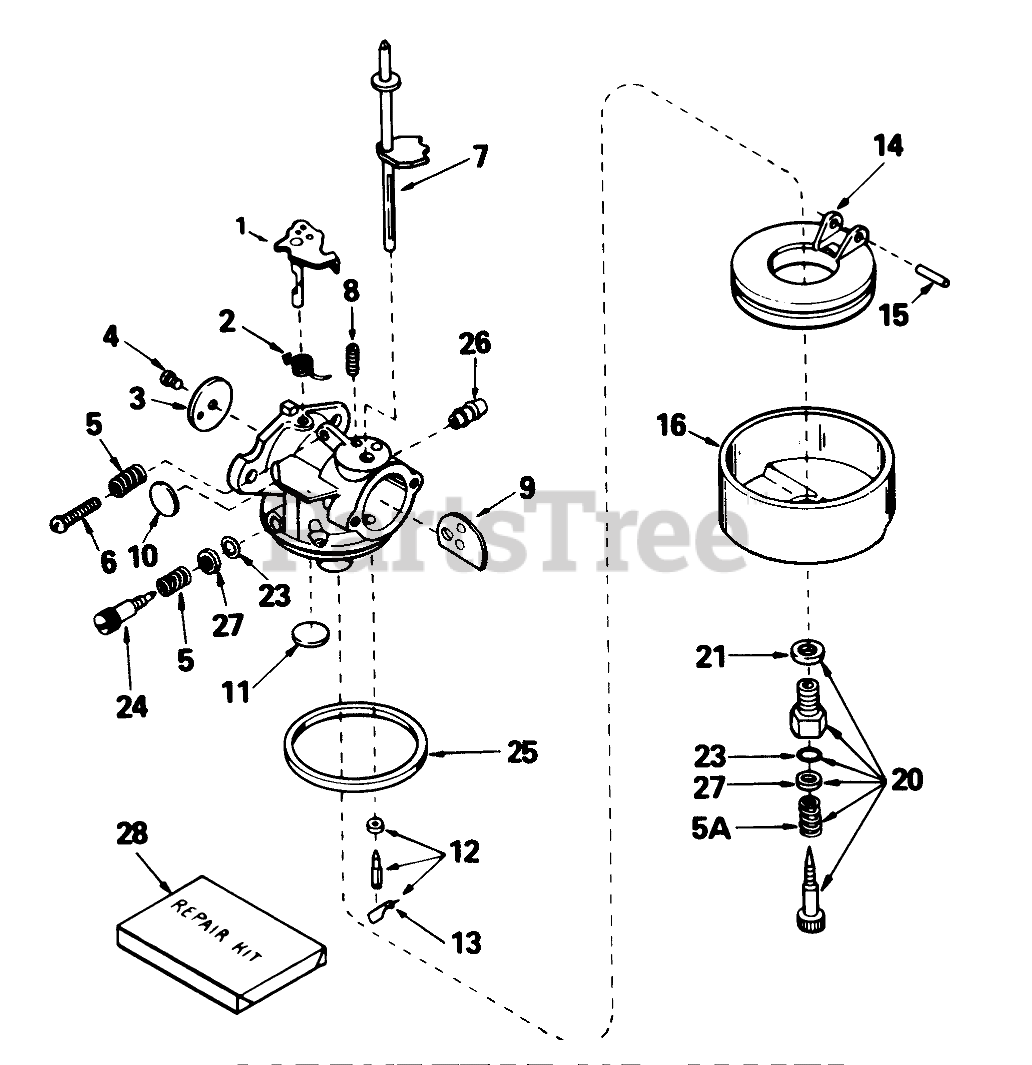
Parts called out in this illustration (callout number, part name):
1	Shaft/Lever-Throttle
2	Spring-Return, Throttle
3	Shutter-Throttle
4	Screw-Shutter
5	Spring-Tension
6	Screw-Throttle Crack Screw / Idle Speed
7	Shaft-Choke
8	Spring-Positioning, Choke
9	Shutter-Choke
10	Plug-Welch, Idle Mixture Well
11	Plug-Welch, Atmospheric Vent
12	Inlet Needle, Seat & Clip Assy. (Incl. Ref. #13)
13	Clip-Spring
14	Float
15	Shaft-Float
16	Bowl-Float (no drain)
20	Adjustment Screw Assy. (Incl. Ref. #5A, 21, 23 & 27)
21	Washer-Bowl Nut
23	"O"Ring
24	Screw-Idle
25	O Ring-Bowl, Float
26	Fitting-Fuel
28	Kit-Repair
